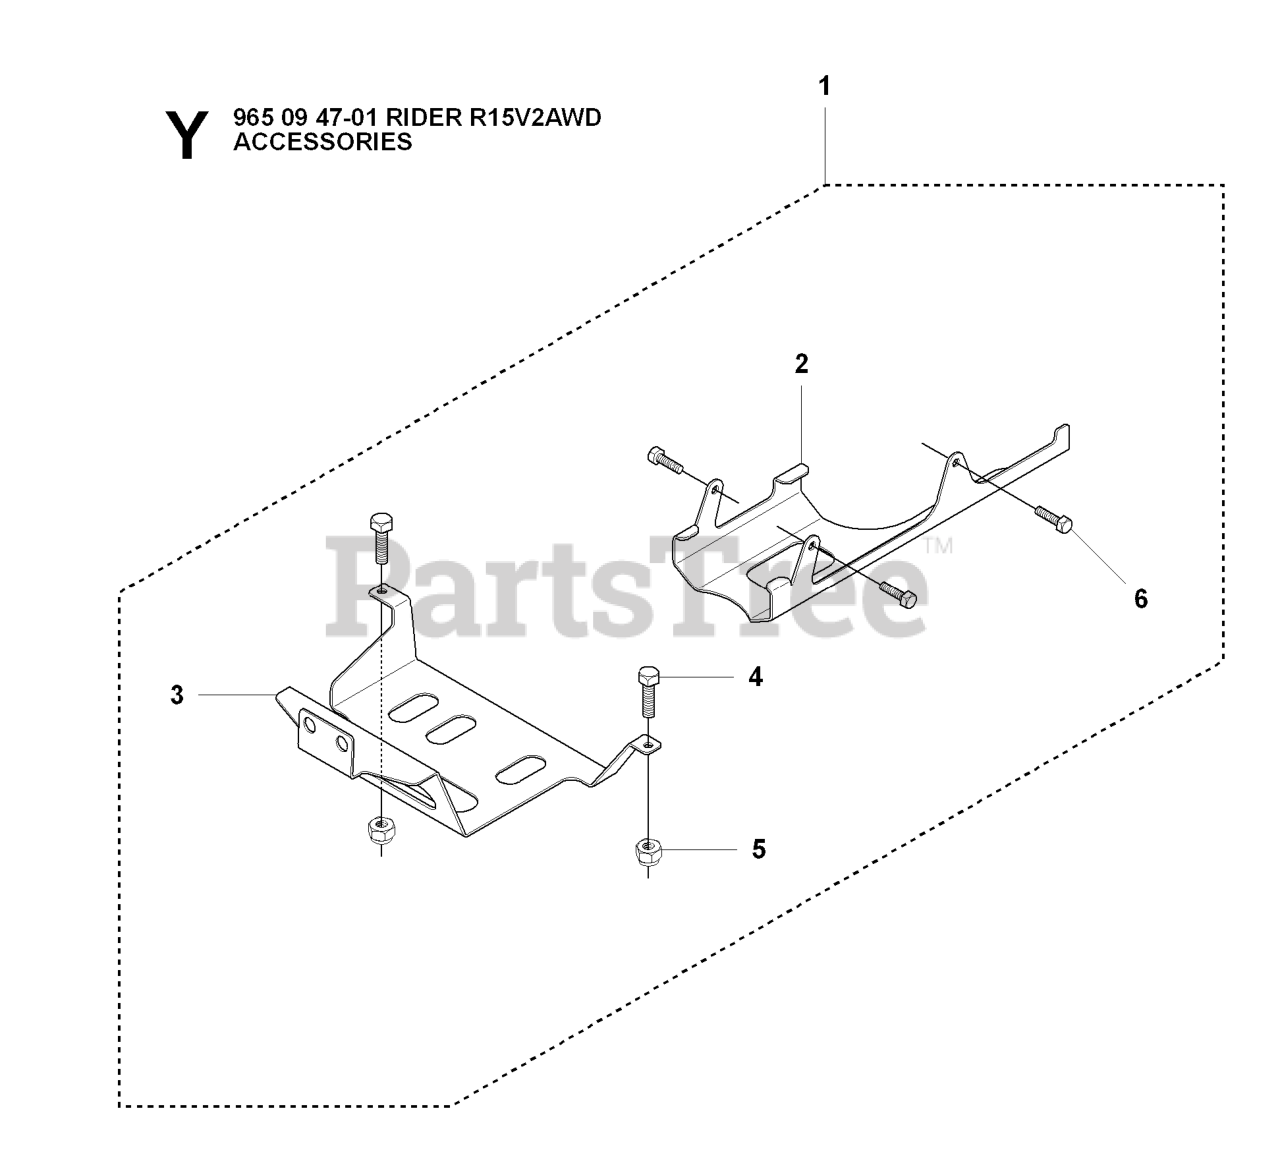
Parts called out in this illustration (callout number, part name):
1	AXLE PROTECTION KIT (R322T)
3	RP PROTECTION PLATE REAR
5	LOCKNUT M8
6	BOLT FLANGE - M8X16
